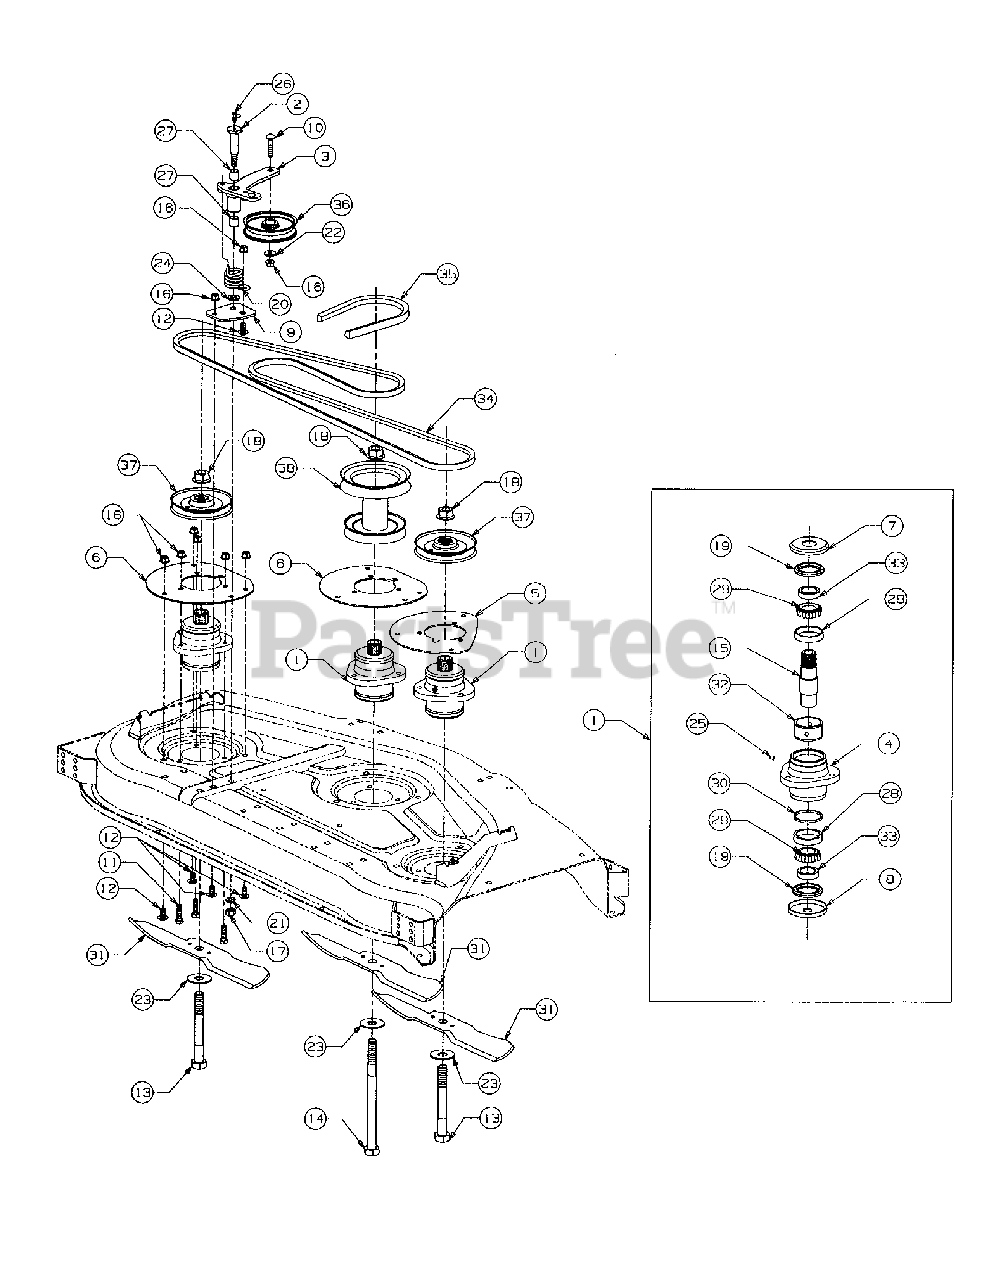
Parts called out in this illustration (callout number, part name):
1	Spindle Assembly, Complete
2	Bolt, Shoulder
7	Cup, Top Spindle
9	Plate, Idler Mtg
10	Bolt, Carriage 3/8-16 x 1.75
11	Screw, Hex Cap 3/8-16 x 1.25 Gr 5
12	Bolt, Sht Nk Carriage, 3/8-16 x .75 Gr 5
13	Bolt, Hex Hd Blade, 3/4-16 x 6.0
14	Bolt, Hex Hd Blade, 3/4-16 x 9.50
15	Shaft, Blade Spindle
16	Nut, Hex Flanged Lock, 3/8-16
17	Nut, Hex 7/16-14 Gr 5
18	Nut, Hex Flange 3/4-16
19	Seal, Oil
20	Spring, Torsion
21	Washer, Lock 7/16
22	Washer, Spec .378 x 1.0 x .125 Thk
23	Washer, Flat .781 x 2.0 x .105 Thk
24	Washer, Flat .469 x .875 x .105 Thk
25	Fitting, Lube
26	Fitting, Lube 90Deg, 1/4-28 Tapper Thd
27	Bearing, Sleeve
28	Cup, Bearing
29	Cone, Bearing
30	Spacer, Bearing
31	Blade, Mower, 16.5
31	Blade, Mower, Hard Coated 16.5
31	Blade, Mower, Hi-Lift 16.5
32	Spacer, Bearing Cup
33	Ring, Seal
34	Belt, Spindle A-Sect X 107.3
35	Belt, PTO, B-Sect x 62.04
36	Pulley, Flat Idler
37	V-Pulley, 4.65 OD
38	Pulley, Deck 5.07 OD & 5.75 OD
